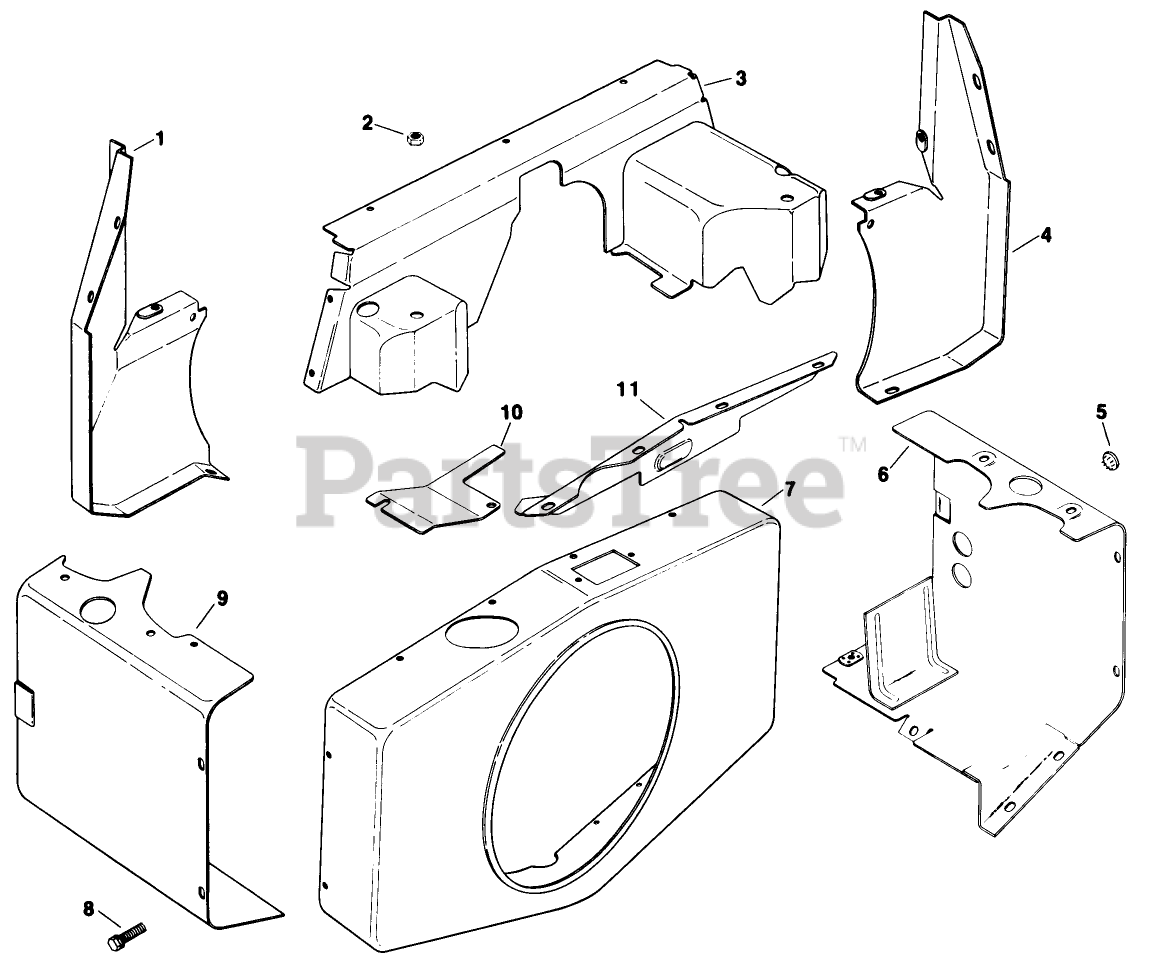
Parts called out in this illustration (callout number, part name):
1	Duct-#2 Side Air
2	Nut
3	Cover-Air Duct
4	#1 Side-Air Duct
5	Button-Plug
6	Baffle-#1 Cylinder Head
7	Housing Blower
8	Screw
9	Baffle-#2 Cylinder Head w/Rear Cylinder Baffle
10	Baffle-Cylinder Head
11	Support-Upper Housing
